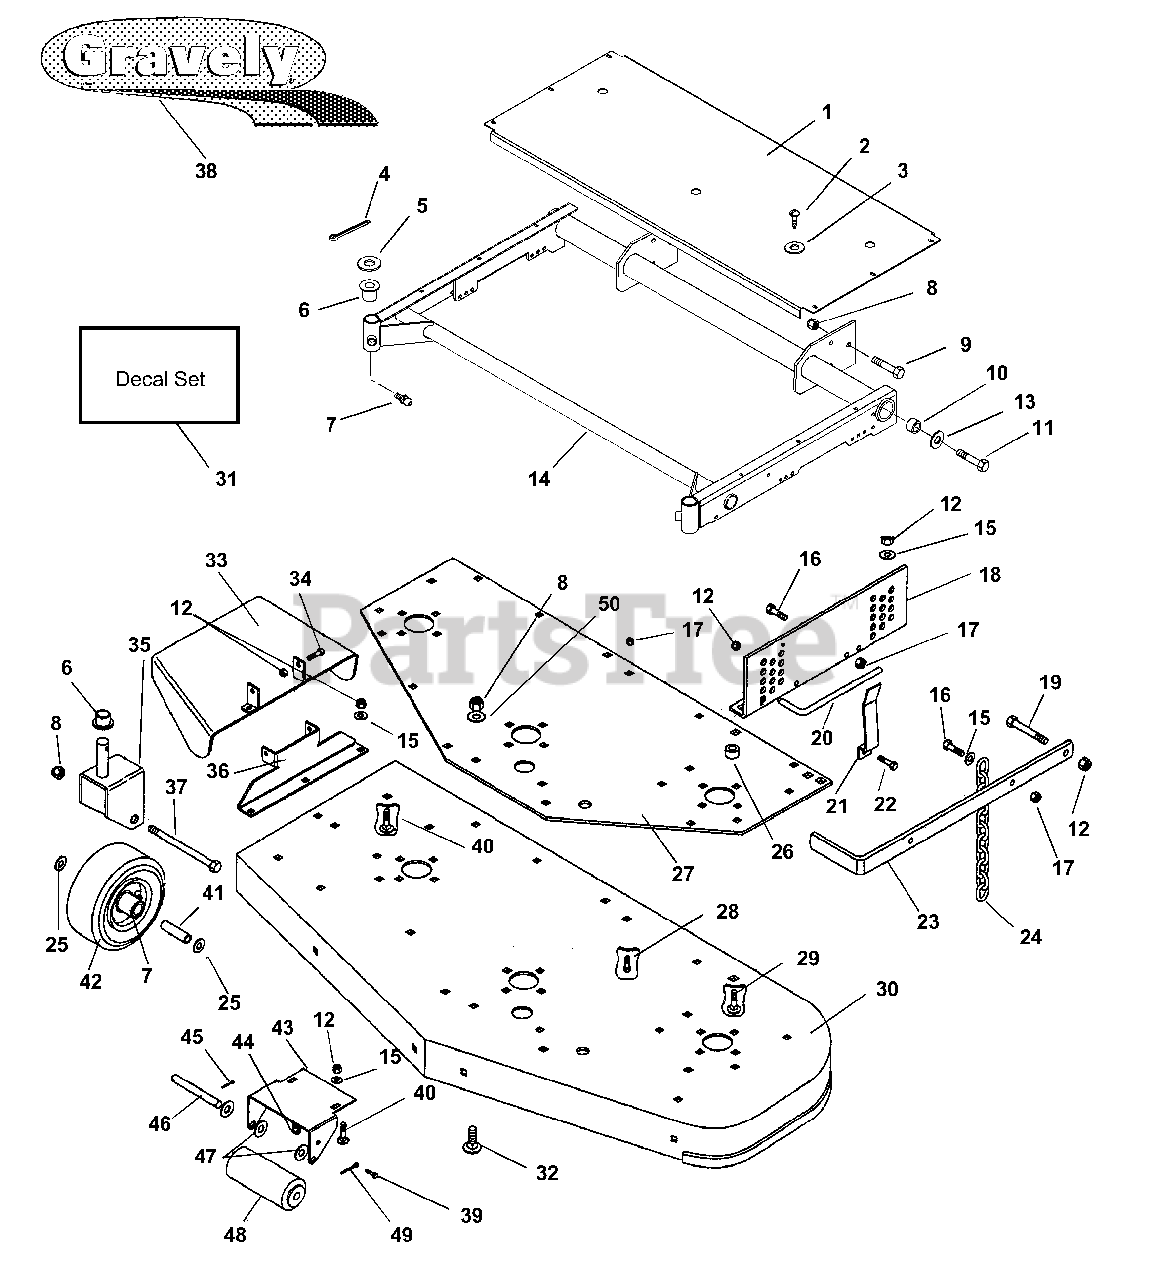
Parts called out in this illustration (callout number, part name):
1	Guard, Belt 60"
2	Screw-Tap .250-20 x .50
3	Washer-Flat-Steel .281 x .625 x .065
4	Pin-Cotter .188 x 1.500
5	Washer-Hardened-Thrust 1.002 x 1.552 x .030
6	Bushing-Flange 1.020 x 1.385 x .75 x 1.75
7	Fitting-Lube .25-28 x .256
8	Nut-Locking-Nylon .50-13 Grade 5
9	Bolt-Hex .50-13 x 1.50 Grade 5
10	Bushing .391 x .626 x .670
11	Bolt-Hex .38-16 x 1.50 Grade 5
12	Nut-Locking-Nylon .375-16 Grade 2
13	Washer-Flat-Steel .390 x 1.5 x .125
14	Weldment, Mower Frame
15	Washer-Flat-Steel .406 x .812 x .065
16	Bolt-Hex .31-18 x 1.00 Grade 5
17	Nut-Locking-Nylon .312-18 Grade 2
18	Bracket, Mower Support Left Hand
18	Bracket, Mower Support Right Hand
19	Bolt-Hex .38-16 x 2.0 Grade 5
20	Pin, Mower Locking
21	Spring, Pin
22	Bolt-Hex .38-16 x .75 Grade 5
23	Bar, Lift
24	Chain, Height Adjuster
25	Washer-Hardened .760 x1.25 x .094
26	Bushing .406 x .750 x .188
27	Plate, 60" Support
28	Bolt-Hex .31-18 x .75 Grade 5
29	Bolt-Round Head Square Neck .38-16 x 1.25
30	Weldment, 60" Mower
31	Decal Set - Deck
32	Bolt-Round Head Square Neck .50-13 x 1.00
33	Weldment, Discharge Chute
34	Bolt-Hex .375-16 x 1.00 Grade 5
35	Weldment, Caster Fork
36	Bracket, Discharge
37	Bolt-Hex .50-13 x 5.50
38	Decal, Gravely Logo
39	Bolt-Hex .25-20 x .75 Grade 5
40	Bolt-Round Head Square Neck .38-16 x 1.0
41	Bearing, Gauge Wheel .750 x .532 x 3.97
42	Wheel 9 x 3.50
43	Bracket, Roller Right Hand
44	Nut-Locking-Nylon .250-20 Grade 2
45	Pin-Cotter .25 x 1.00
46	Shaft, Center Roller
47	Washer-Flat-Steel .656 x 1.312 x .095
48	Roller, Gauge
49	Pin-Cotter .250 x 2.00
50	Washer-Flat-Steel .50 x 1.25x .083
